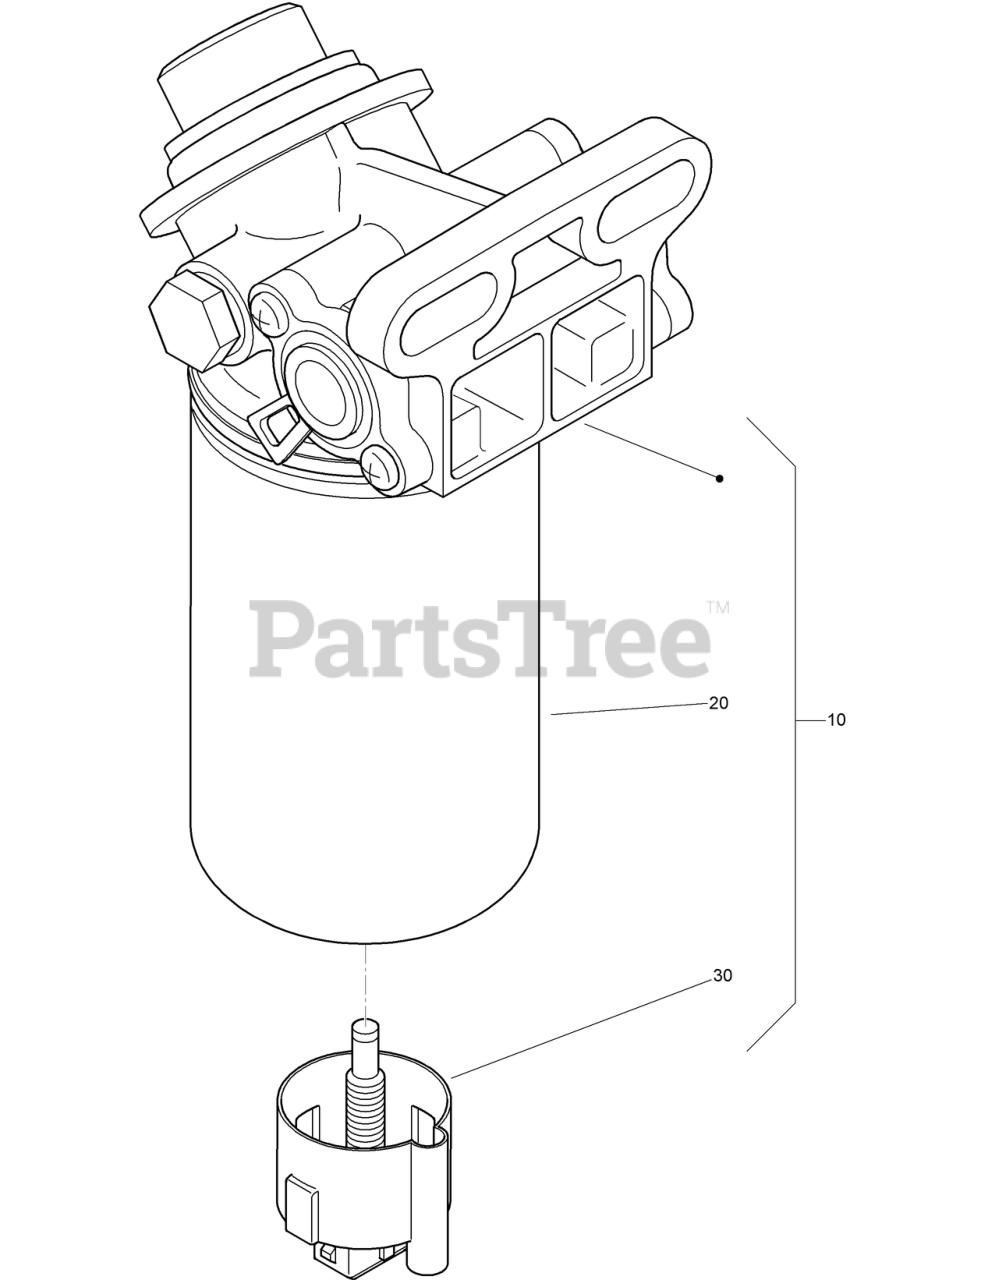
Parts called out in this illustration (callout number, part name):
10	FILTER-SEPERATOR, WATER
20	FILTER-SEPARATOR
30	SWITCH ASM
